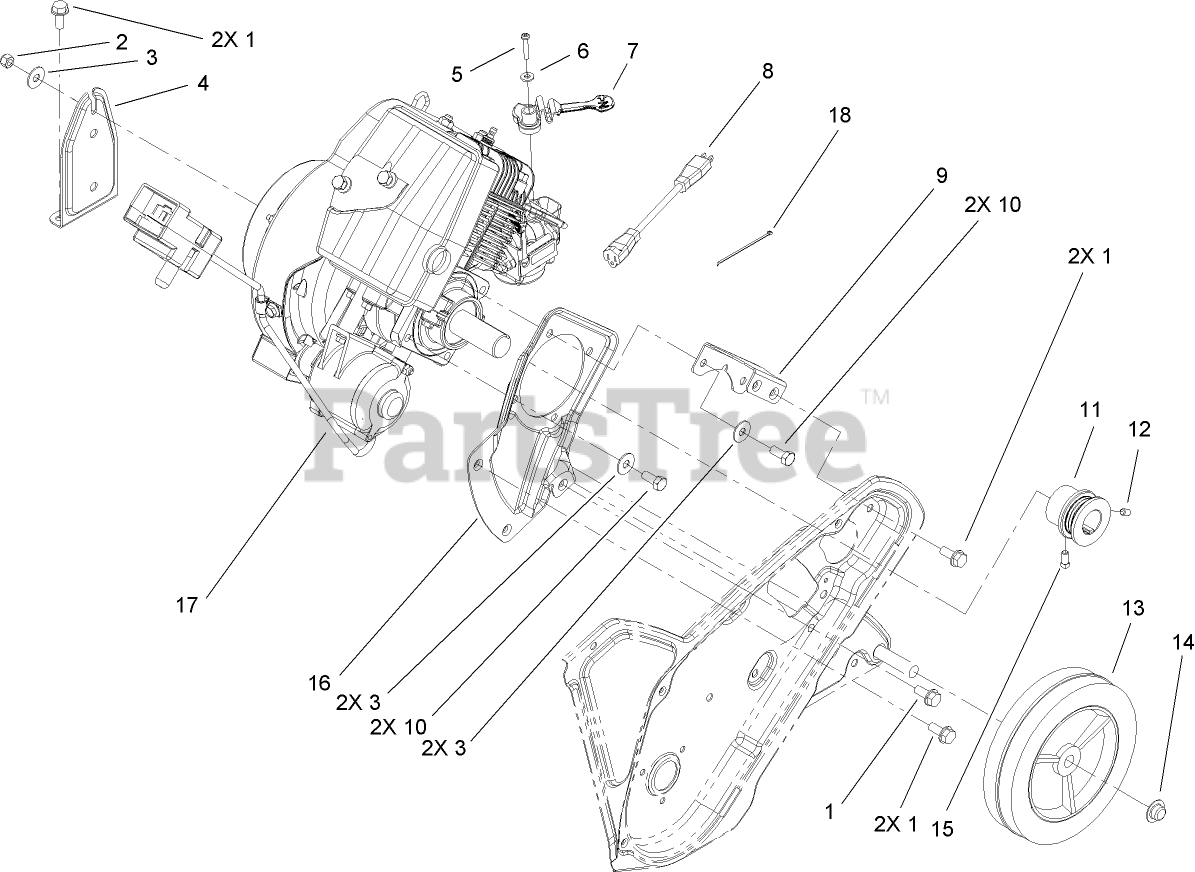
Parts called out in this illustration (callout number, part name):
1	SCREW-THD ROLL, HWH
2	NUT-LOCK, NI
3	WASHER-BELLEVILLE
4	BRACKET-RECOIL
5	SCREW-PPH, PLASTITE
6	WASHER-FLAT
7	LEVER-CHOKE
8	CORD-EXTENSION (only on: 38078)
9	SUPPORT-ENGINE, SIDE
10	SCREW-HH
11	PULLEY-3 GROOVE
12	SCREW-HSH
13	WHEEL
14	NUT-PUSH
15	SCREW-SQH
16	PLATE-ENGINE, PTO
17	Loose Parts Package
18	TIE-CABLE
